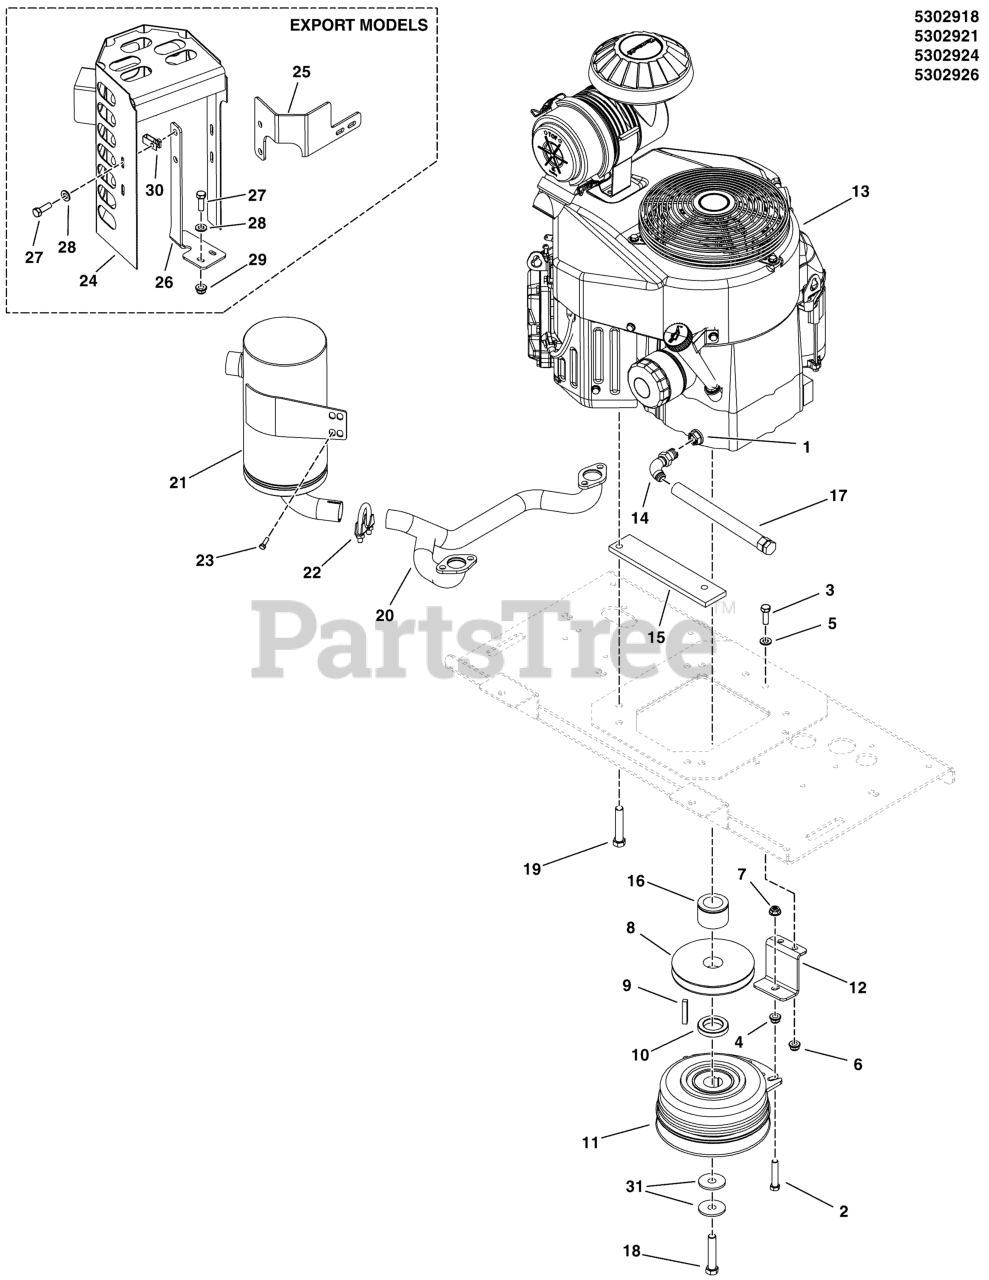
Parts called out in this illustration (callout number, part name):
1	ADAPTER-OIL DRAIN
2	BOLT, 5/16-18 X 1-1/2 GD5 YZ
3	BOLT, 5/16-18 X 1 GD5 YZ
4	NUT, 3/8-16 HEX JAM
5	WASHER, 5/16" SAE
6	NUT, 5/16-18 HEX NYLOCK FLANGE
7	NUT, 3/8-16 HEX NYLOCK FLANGE
8	PULLEY, CRANKSHAFT, 1.125 ID X 4.75 OD
9	KEY, 1/4 SQ X 5/8
10	SPACER, 1.13 X 1.75 X .32
11	* CLUTCH, 5218-134, WARNER
12	PLATE, CLUTCH ANCHOR, DDS
14	FITTING, 3/8NPT ELBOW, M-F
15	SPACER, ENGINE BLOCK, CCW
16	SPACER, 1.13 X 1.75 X 1.625, CZ
17	HOSE, OIL DRAIN
18	BOLT, CRANKSHAFT,7/16-20X2-1/2, GD8
19	BOLT,HEX FLG,SER GD5 3/8-16X2, PATCH,CZ
20	MANIFOLD, KAWASAKI, VERTICAL, CCW
21	MUFFLER, KAWASAKI, VERTICAL, CCW
22	CLAMP, EXHAUST EXTENSION
23	SCREW
24	WELD, MUFFLER GUARD
25	PLATE, BRACKET, FRONT - RED
26	PLATE, UPPER BRACKET, CCW - RED
27	BOLT, 1/4-20 X 1" GD5 CZ
28	WASHER, 1/4 SAE
29	NUT, 1/4-20 HEX NYLOCK FLANGE
30	BODY CLIP, 1/4-20 X 1/2 DEEP
31	BELLEVILLE WASHER 1.1875 X .442 X .089
